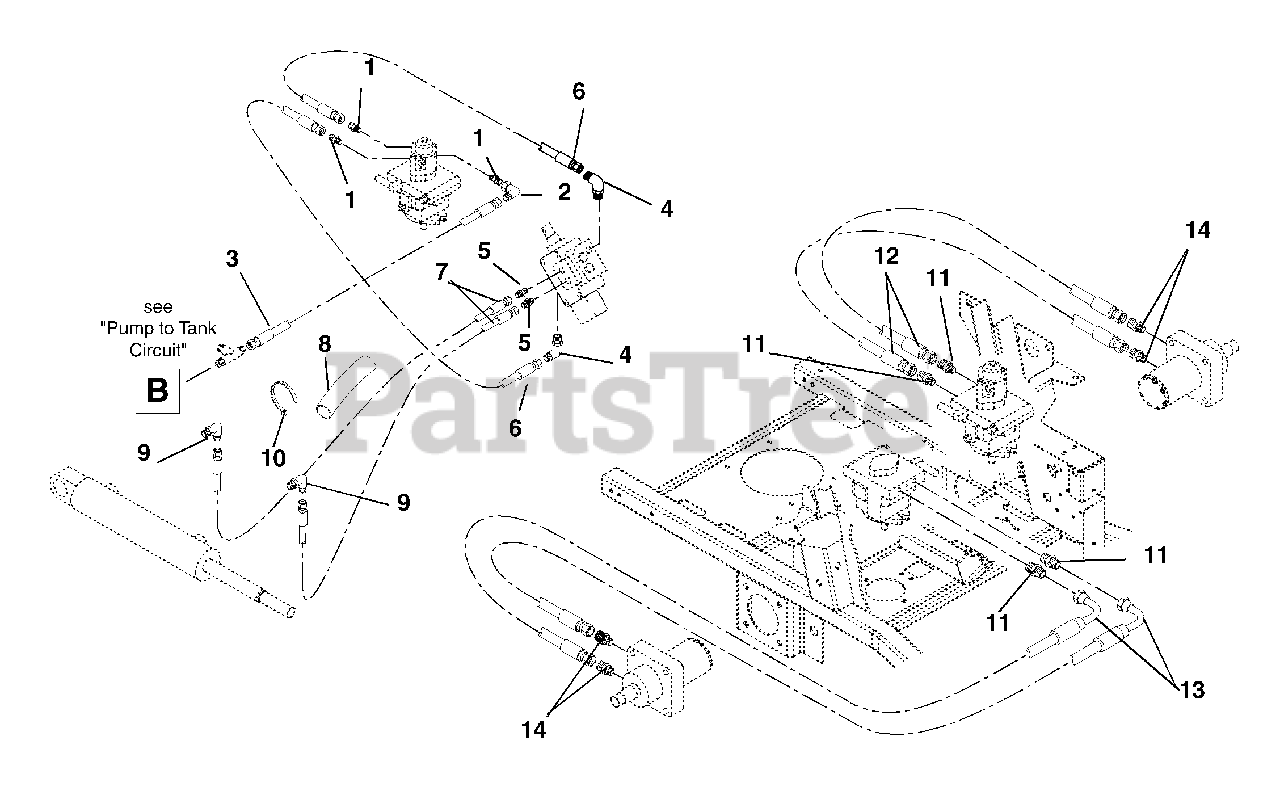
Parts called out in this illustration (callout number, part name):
2	Adapter
3	Hose-Hydraulic Valve to Tank
4	Adapter
5	Adapter
6	Hose Hydraulic .38 27.75 Long
7	Hose-Hydraulic .25 40.5" Long
8	Sleeve Protective 24"
9	Adapter
10	Cable Tie
11	Adapter-Hydraulic Steel .75 to .75
12	Hose-Hydraulic .50 18.75 Long
13	Hose-Hydraulic .50 x 29.50 Long
14	Adapter-Hydraulic Steel .875 to .75
